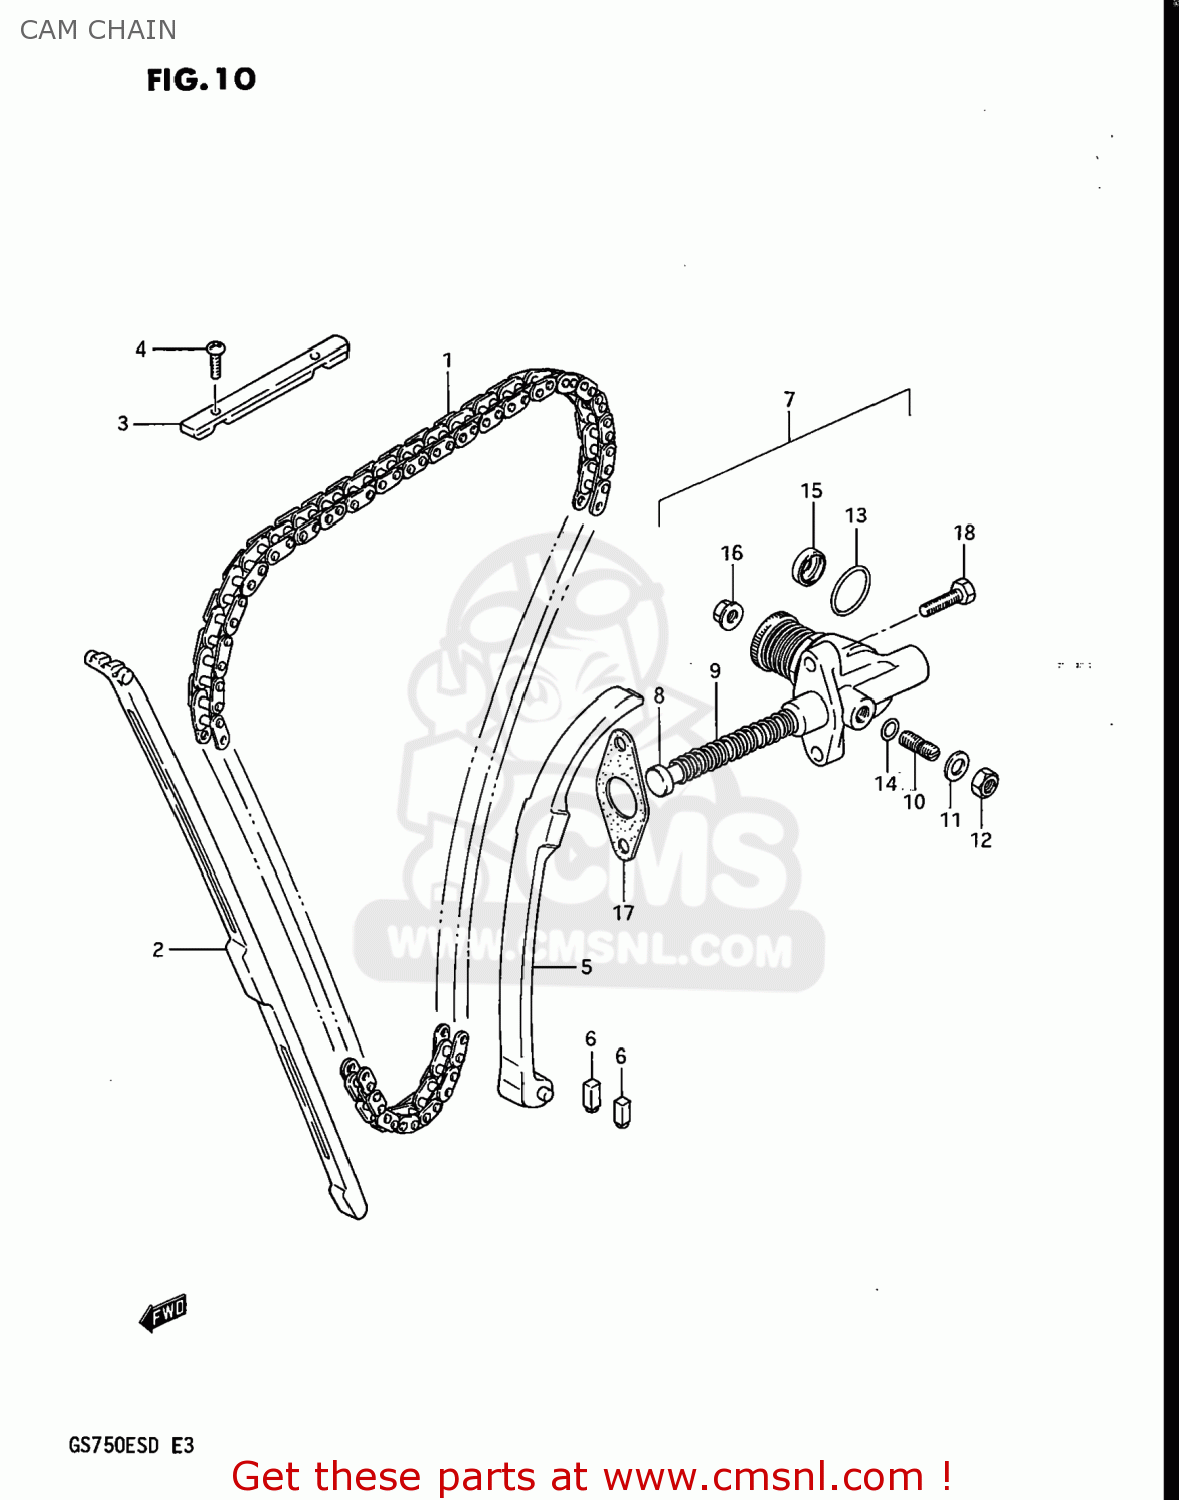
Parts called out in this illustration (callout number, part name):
1	CHAIN,CAMSHAFT DRIVE(120L)
2	GUIDE,CAM CHAIN NO.1
3	GUIDE,CAM CHAIN NO.3
4	SCREW
5	TENSIONER
6	CUSHION,CAM CHAIN TENSIONER
7	ADJUSTER ASSY,TENSIONER
8	ROD,PUSH
9	SPRING
10	SCREW,TENSIONER ADJUST
11	WASHER,8.5X16X
12	NUT
13	O RING(D:2.4,ID:20.8)
14	O RING(D:1.9,ID:5.7)
15	SEAL,OIL(10X16X4)
16	NUT
17	GASKET,TENSIONER ADJUSTER (MCA)
18	SCREW
